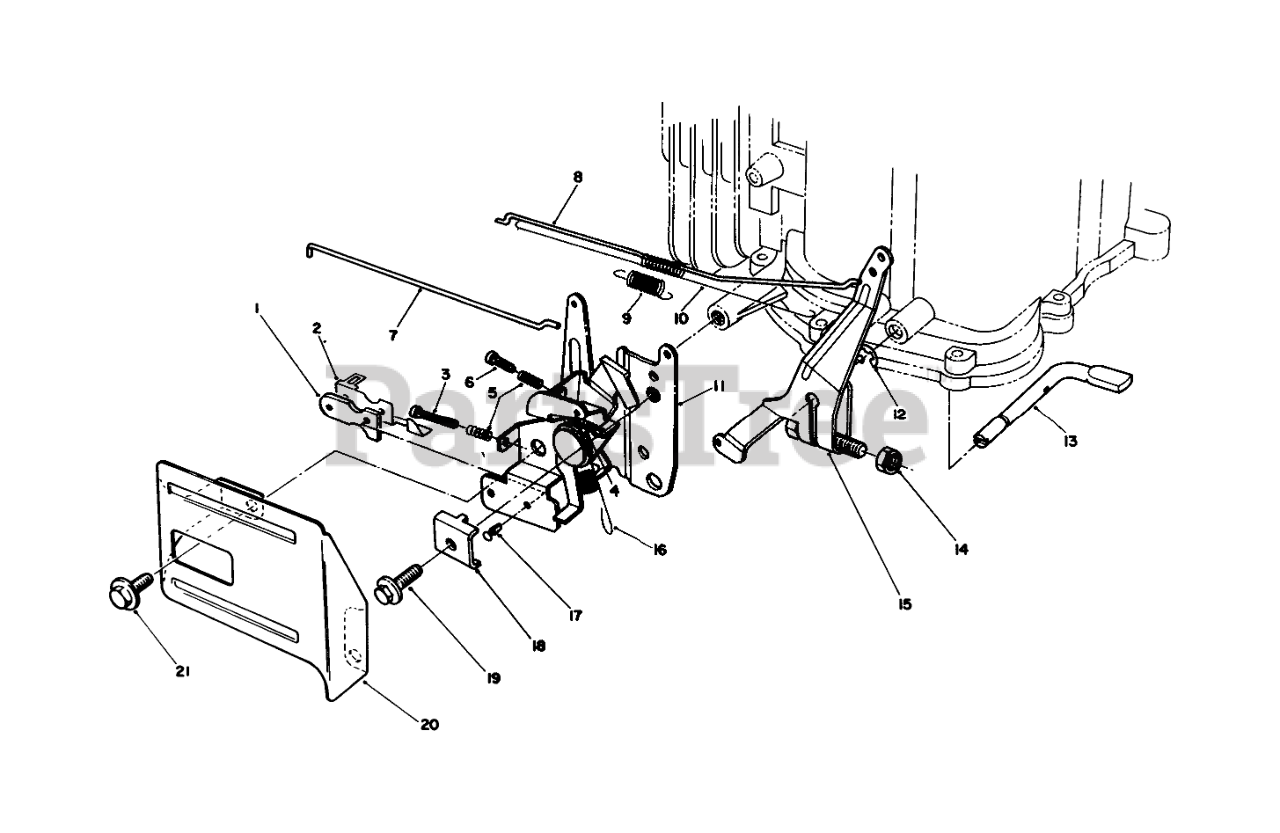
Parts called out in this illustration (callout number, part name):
1	INSULATOR-KILL SWITCH
2	TERMINAL-KILL SWITCH
3	SCREW
4	SPRING
5	SPRING
6	SCREW
7	Rod-Choke
8	Rod-Carburetor
9	SPRING
10	SPRING
11	THROTTLE
12	E-RING
13	SHAFT
14	Nut
15	ARM ASM
16	SPRING
17	RIVET
18	CLAMP-CABLE
20	THROTTLE GUARD
